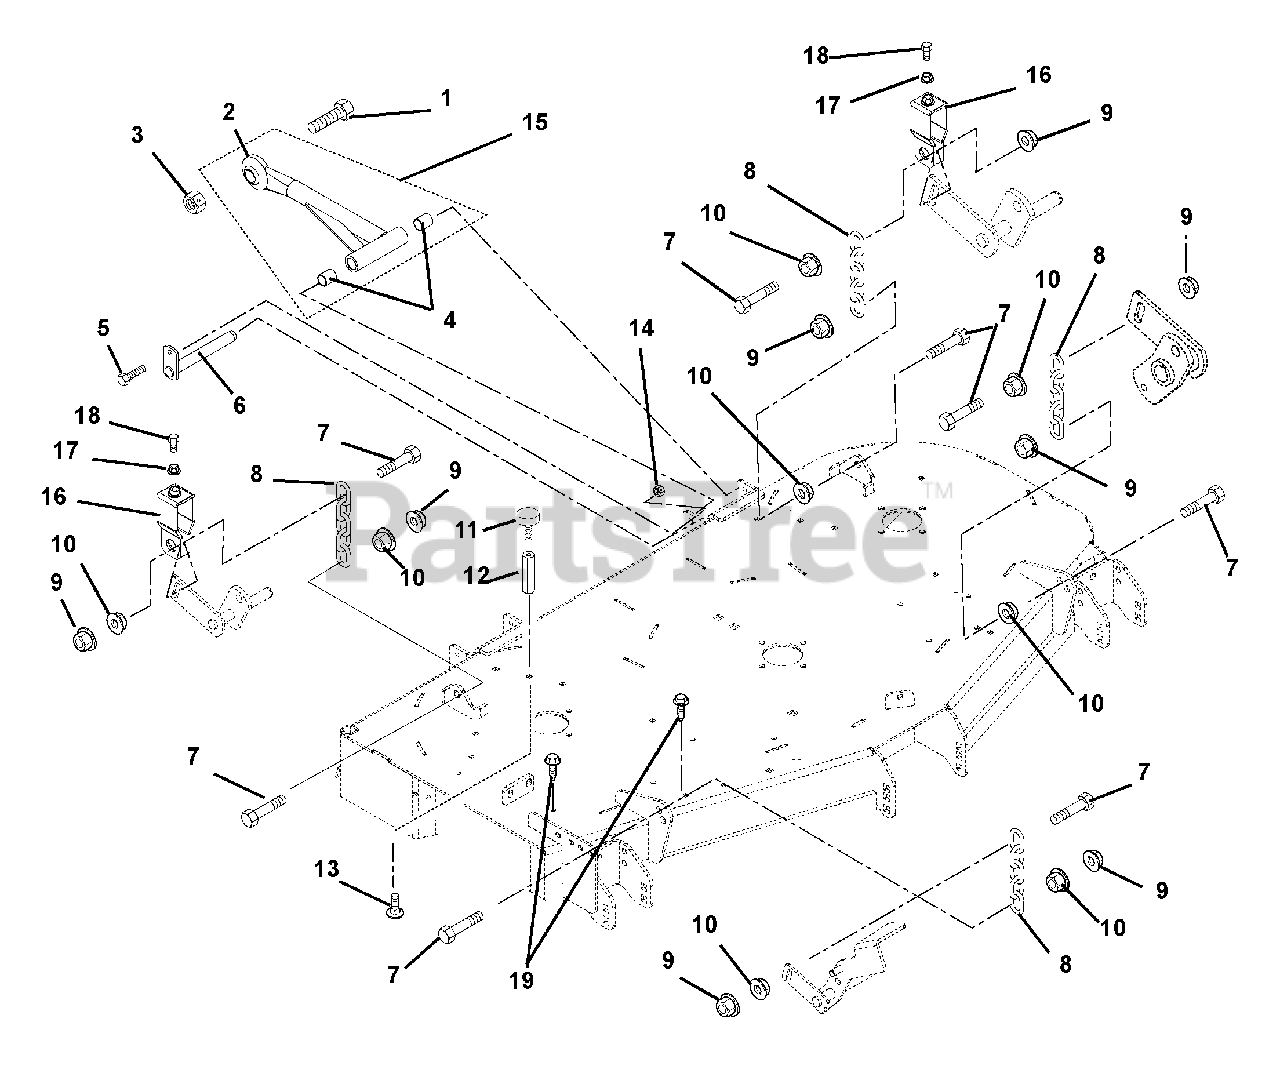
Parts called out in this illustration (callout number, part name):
1	Bolt, Hex .875-9 x 2.75 Grade 5
2	Mower Mounting Arm Weldment
3	Nut, Locking-Center .875-9
4	Bearing, .75 x .875 x 1.00
5	Bolt, Hex .38-16 x .75 Grade 5
6	Weldment, Mower Mounting Pin
7	Bolt, Hex M12-1.75 x 50 Grade 5
8	Chain, Link
9	Nut, Locking-Top-Flange M12-1.75
10	Nut, Spin Lock-Flange M12-1.75
11	Bumper, Rubber
12	Nut, Coupling .31-18 x 3.00
13	Bolt, Round Head Square Neck .31-18 x .75 Loctite with Epoxy Patch
14	Nut, .38-16 Nyloc Flange
15	Assembly, Mower Mounting Arm
16	Bracket, Deck Leveling
17	Nut-Jam .312-18
18	Bolt, Hex .31-18 x 1.75 Full Thread
19	Screw, Tapping .38-16 x .50 Hex Washer Head Thread
19	Screw-Tapping .38-16 x .50 Hex Washer Head Thread
